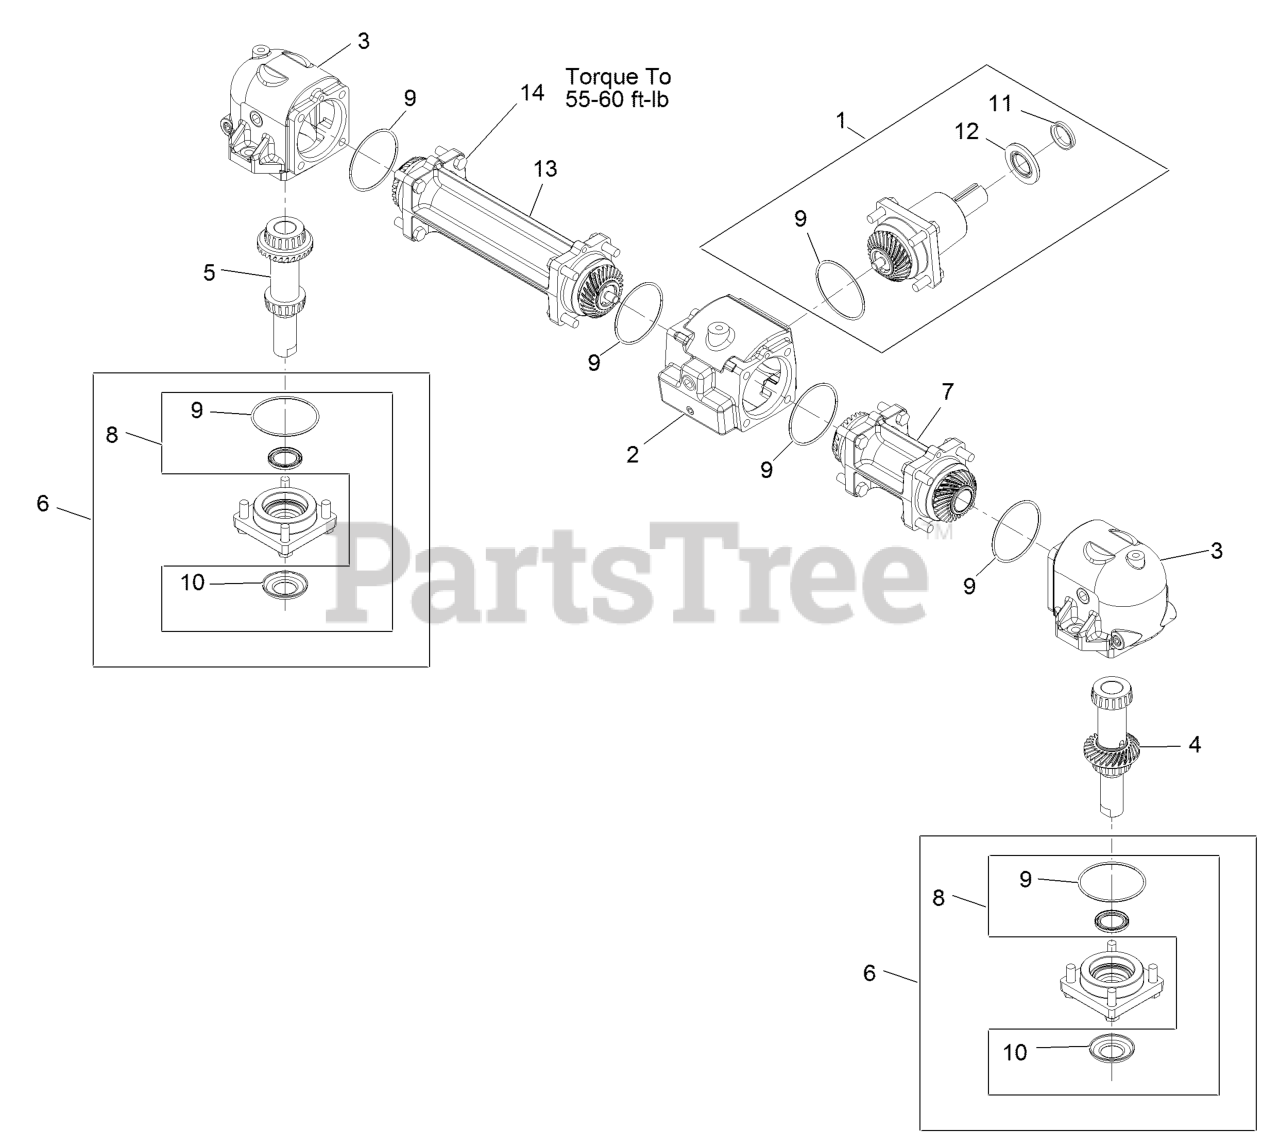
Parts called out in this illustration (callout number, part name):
1	PINION-INPUT
2	HOUSING-CENTER
3	HOUSING-END
4	OUTPUT SHAFT AND GEAR-LH
5	OUTPUT SHAFT AND GEAR-RH
6	CAP-OUTPUT
7	TUBE-CONNECTOR, SHORT
8	OUTPUT SEAL KIT
9	SEAL-O-RING
10	WASHER-CUPPED
11	SEAL-V-RING
12	SEAL-INPUT
13	CONNECTOR-TUBE, LONG
